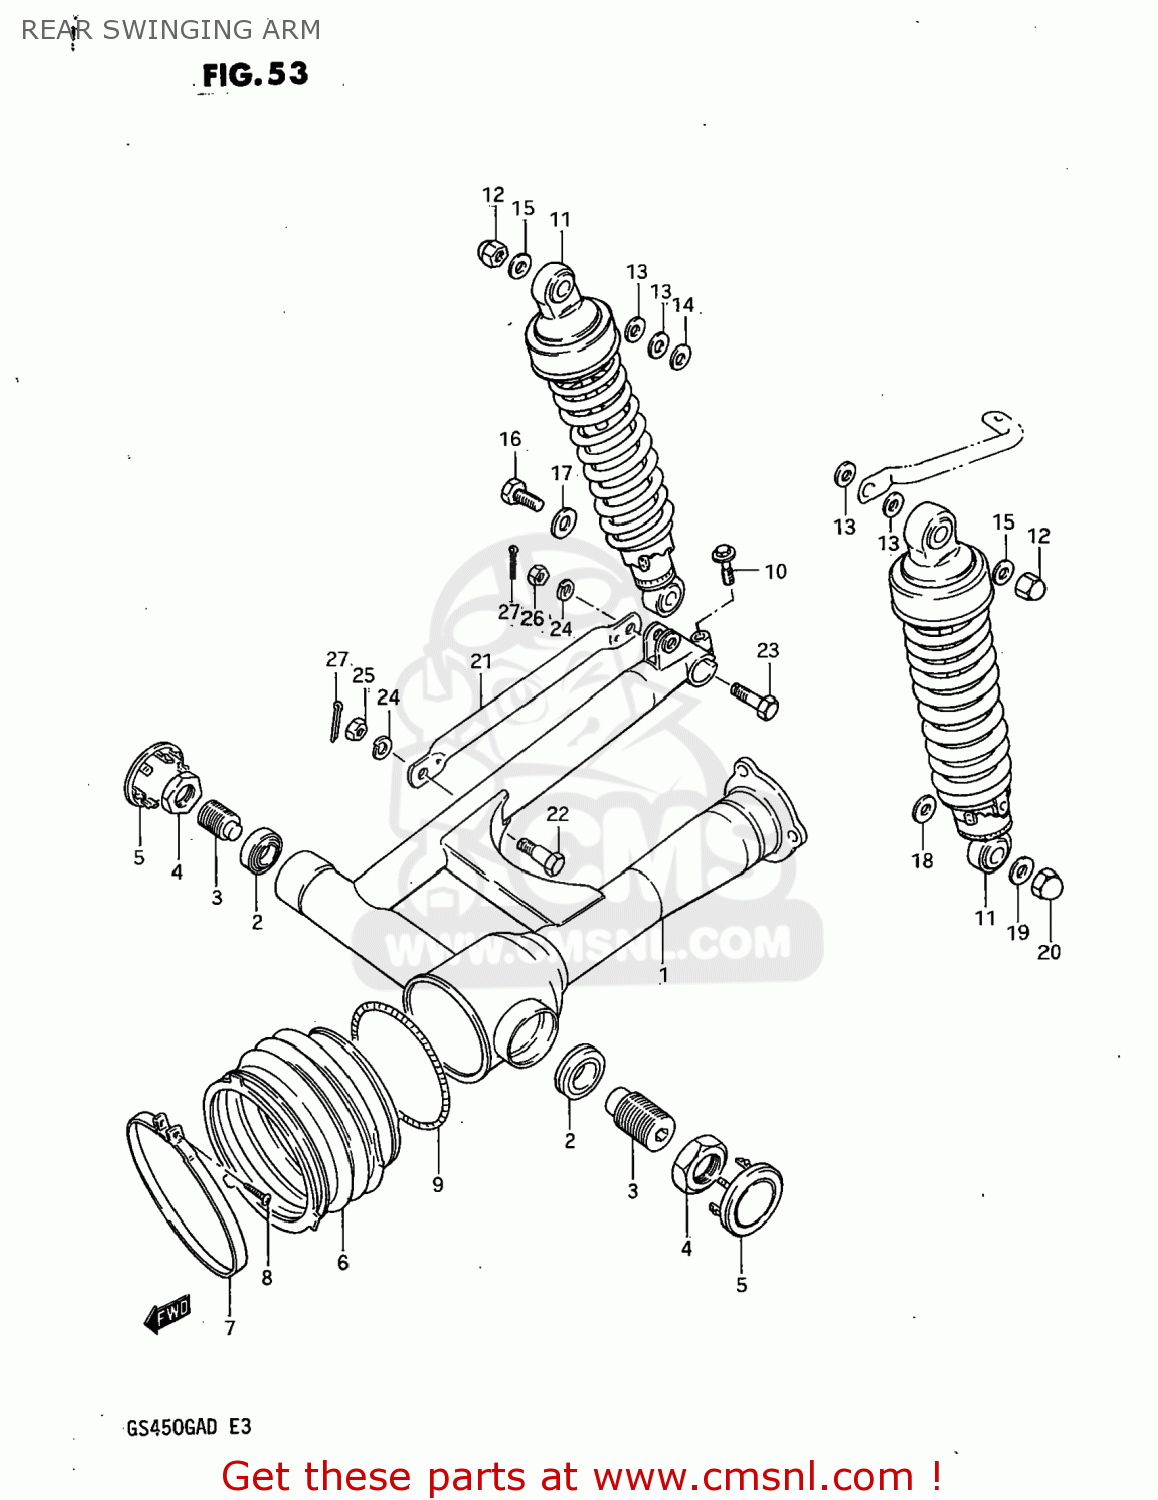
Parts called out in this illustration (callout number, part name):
1	SWING ARM ASSEMBLY,REAR
2	BEARING(15X35X11.75)
3	BOLT,REAR SWING ARM PIVOT
4	NUT (22MM)
5	CAP,REAR SWING ARM PIVOT
6	BOOT,PROPELLER SHAFT
7	CLAMP
8	SCREW 4X25
9	SPRING,PROPELLER SHAFT
10	BOLT
11	ABSORBER ASSEMBLY,REAR SHOCK
12	NUT
13	WASHER
14	WASHER (12.5X24X3.2)
15	WASHER
16	BOLT 12X33
17	WASHER (12.5X24X1.6)
18	WASHER
19	WASHER
20	NUT, LOWER LH
21	TORQUE LINK,REAR
22	BOLT(10X24.5)
23	BOLT(10X31)
24	LOCK WASHER
25	NUT
26	NUT
27	PIN 20X20
